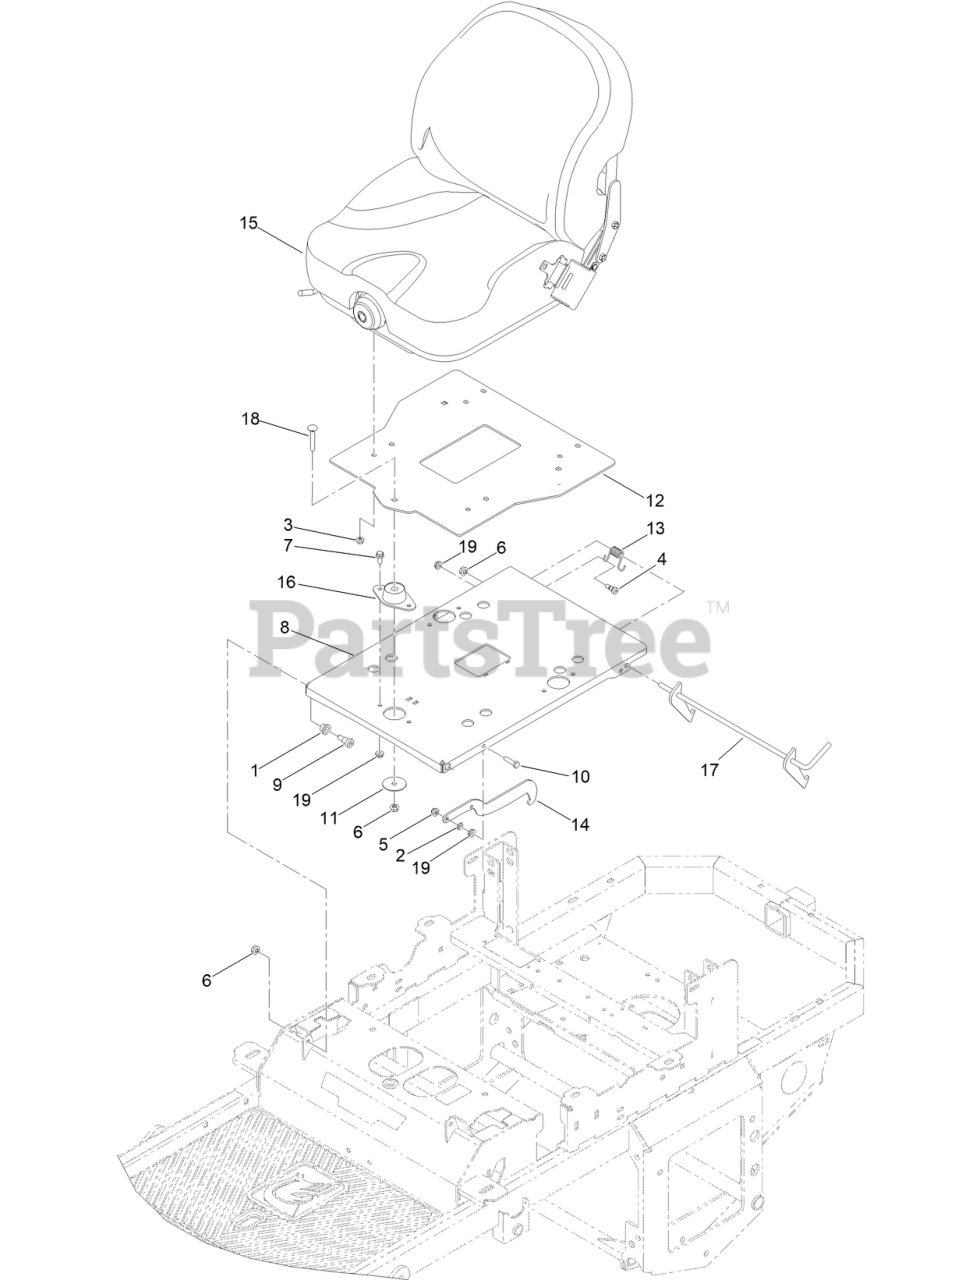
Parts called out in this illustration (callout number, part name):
1	1/2IN ID X 5/8IN OD X 1/2IN FLANGE BUSH
2	.312IDX.625ODX.062 THK THRUST BRG OI BRZ
3	5/16-18 NYLON INSERT FLANGE L/NUT ZC
4	SCREW-HSH
5	NUT-HF, NI
7	SCREW-HHF
8	ASM, PLATE-SEAT BASE UPGRADE W/ DECALS
8	2019 UPGRADE SEAT BASE PLATE PAINT
9	1/2 X 1/2 SOCKET SHOULDER BOLT ZC YELLOW
10	SCREW-HH
11	3/8 X 2IN OD FENDER WASHER YZ
12	2019 UPGRADE SEAT PLATE PAINT
13	MWR SEAT LATCH SPRING
14	MWR SEAT LATCH HOOK PAINT
15	2019 FULL SUSP SEAT
16	FLOATING SEAT DAMPER-STIFFER
17	MWR SEAT LATCH RELEASE ASSY ABC
18	SCREW-CARR
